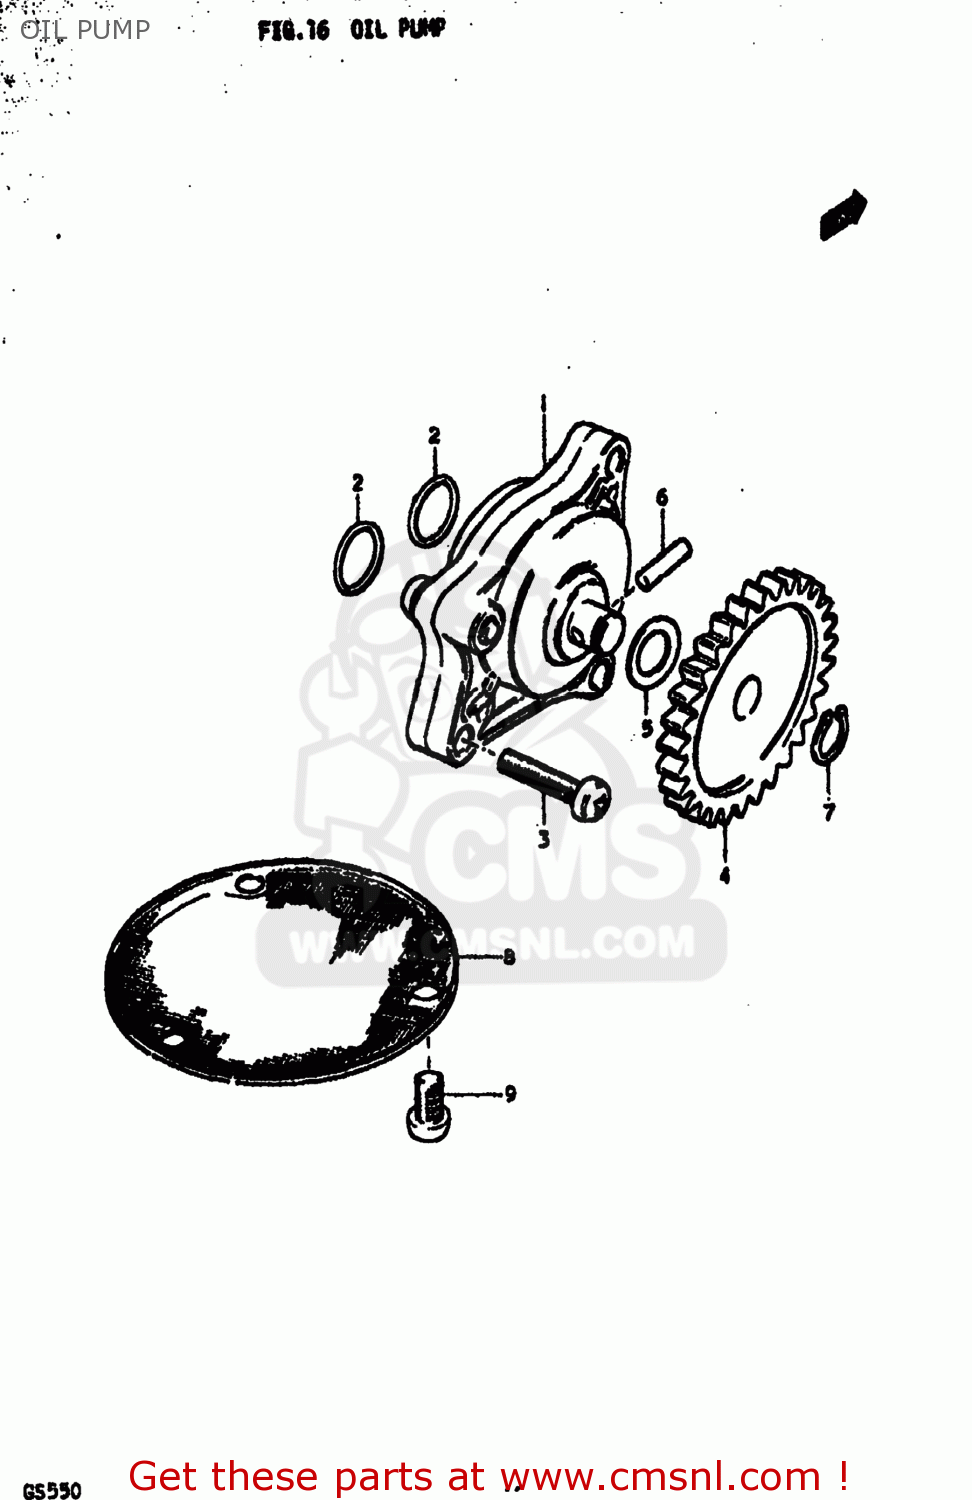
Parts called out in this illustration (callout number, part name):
1	PUMP ASSEMBLY,OIL
2	O RING(D:1.9,ID:13)
3	SCREW
4	GEAR,OIL PUMP DRIVEN
5	SHIM
6	PIN(4X15.8)
7	CIRCLIP
8	STRAINER,ENGINE OIL
9	SCREW 6X12
